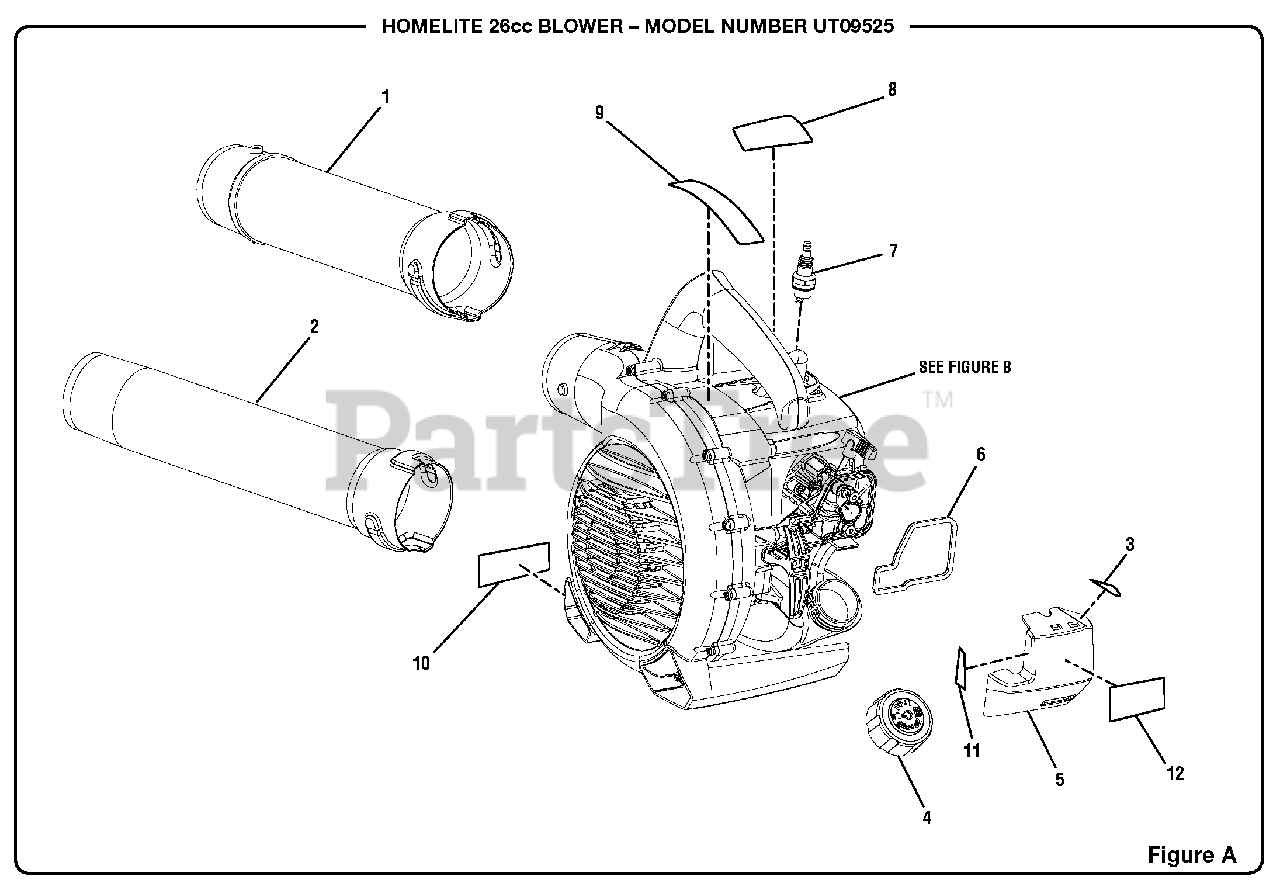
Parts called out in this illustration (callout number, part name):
1	Upper Blower Tube
2	Sweeper Nozzle
3	Throttle Label
4	Fuel Cap Assembly
5	Air Box Cover
6	Air Box Gasket
7	Spark Plug (RCJ6Y)
8	Engine Shroud Label
9	Warning Label
10	Combustion Warning Label
11	Choke Label
12	Starting Instructions Label
